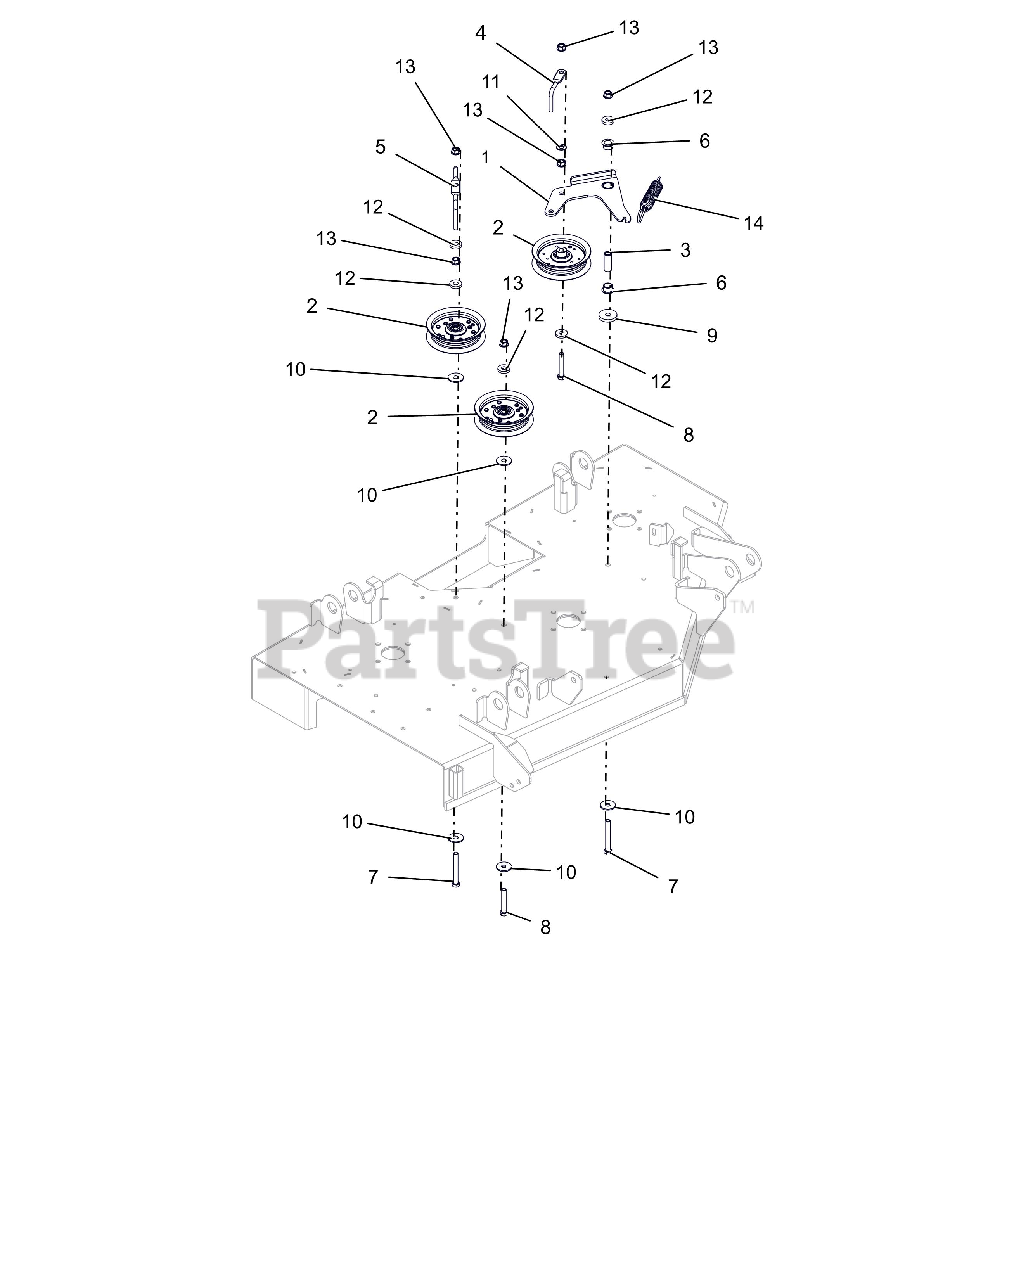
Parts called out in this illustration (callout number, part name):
1	WLDMT, IDLER ARM-42"
2	ASM, IDLER 4"
3	SPACER, .375IDX.625ODX1.66 PM
4	WIREFORM, BELT FINGER
5	WIREFORM, BELT FINGER
6	BSHG-FLG, .625X.750X.500X1.00
7	BLT-HEX .38-16X3.00 GR5 FTH YZ
8	@BLT-HEX .38-16X2.25 GR5 YWZC
9	WSHR,FLT STL.406X1.50X.245YWZC
10	@WSHR-FL-STL .406X1.25X.10 ZC
11	@WSHR-FL-STL.406X.812X.065 YWZ
12	WSHR-FL-STL .406X1.00X.188 YWZ
13	@NUT-LK-TOP-FLG .38-16 YWZC
14	SG-TENS .135X.98X6.0 WLD 62
